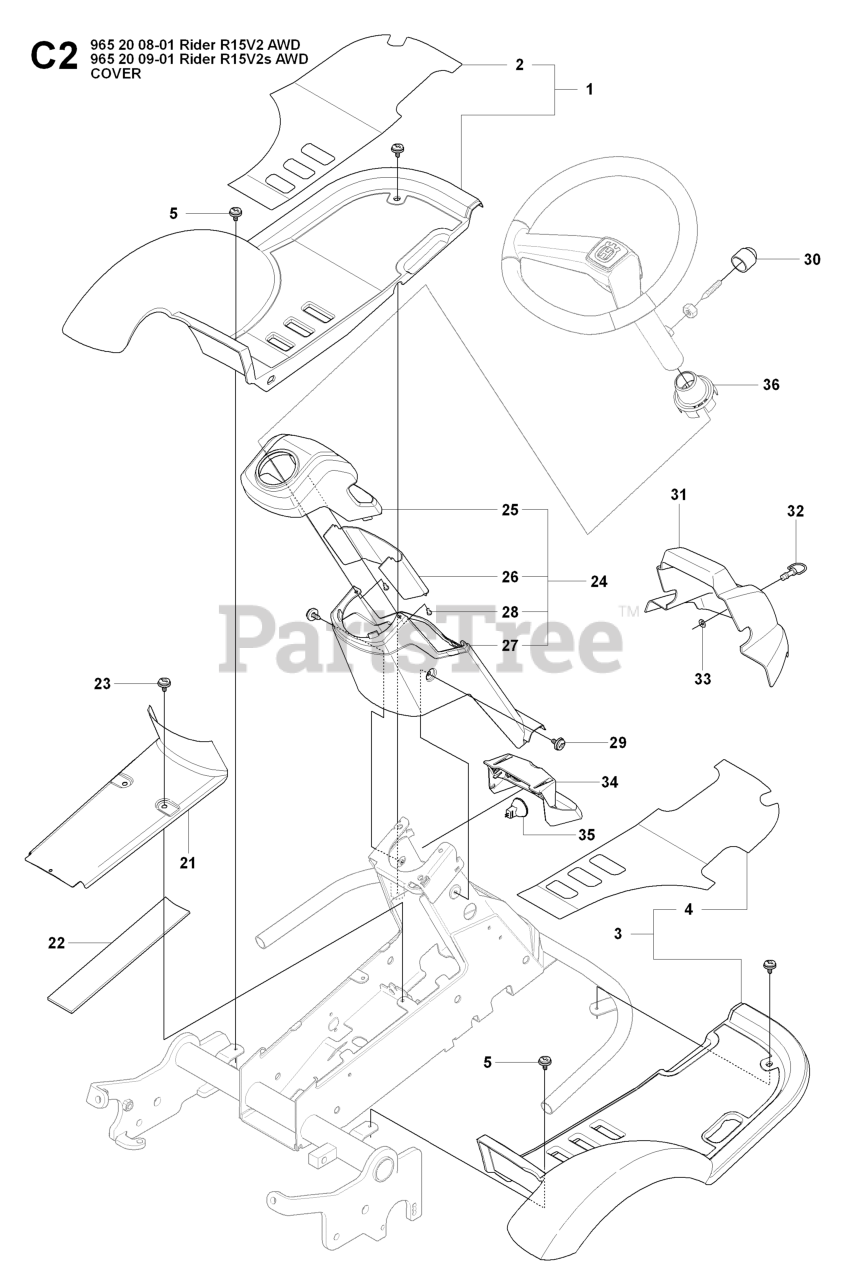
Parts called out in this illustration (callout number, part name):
1	FOOT PLATE
3	FOOT PLATE
30	PROTECTIVE COVER
32	BOLT
